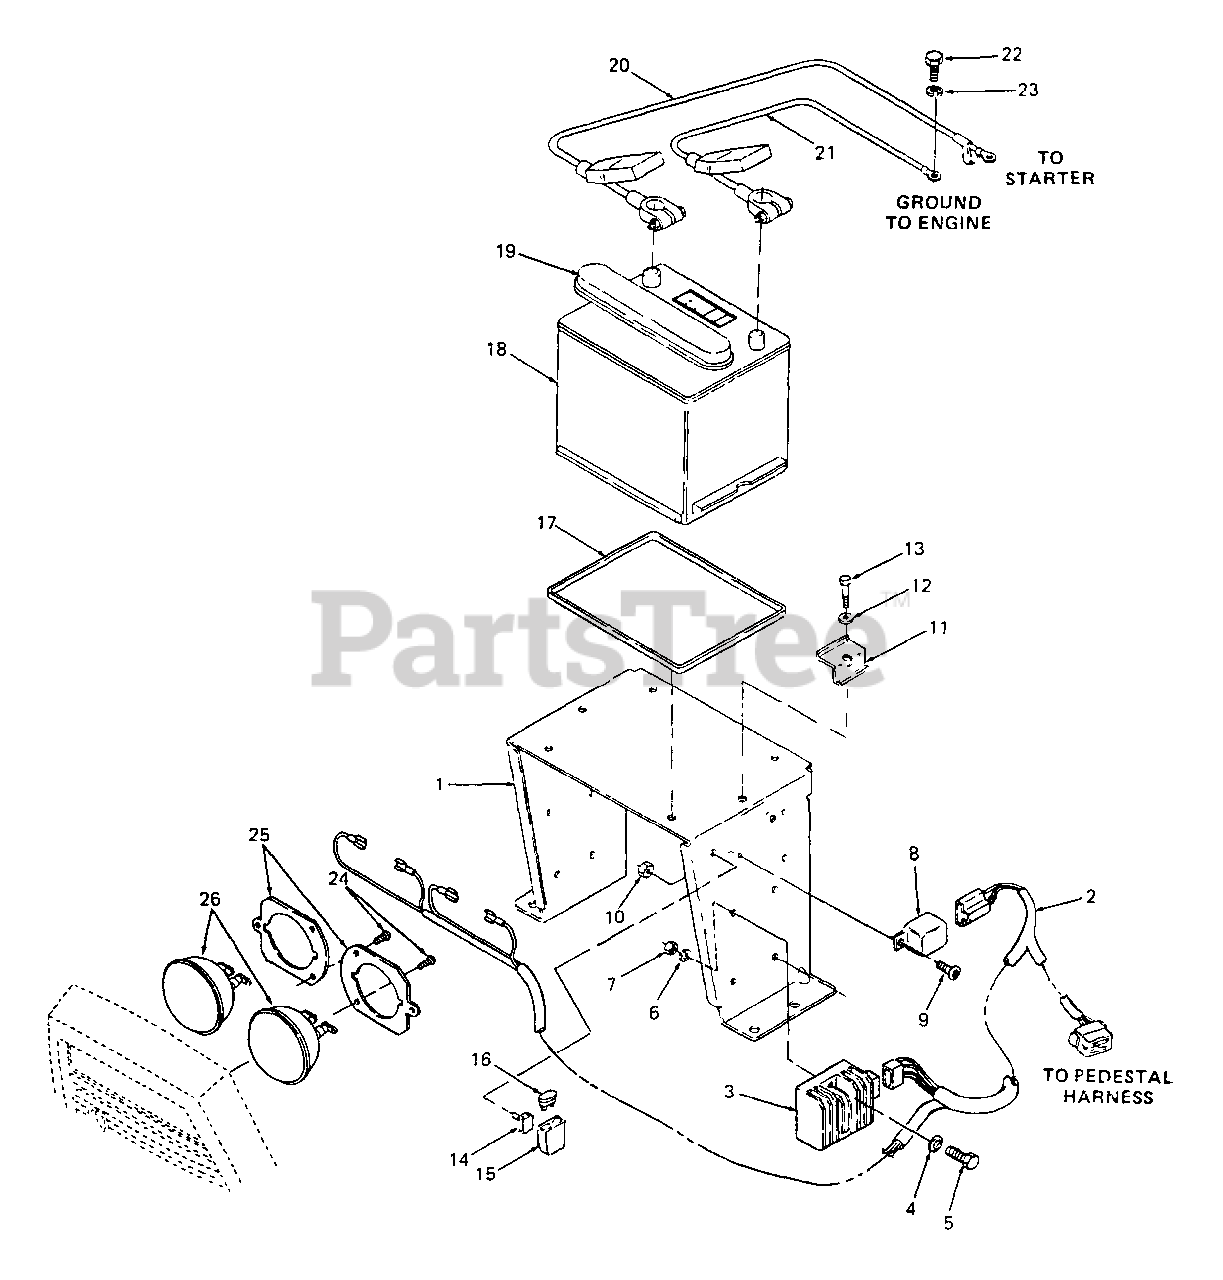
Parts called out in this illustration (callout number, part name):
1	Tray Assy, Battery
2	Harness, Main Wire
3	Regulator, Voltage
4	Washer, Bell, .265 x .75 x .062 Thk
5	Screw, Hex Cap, 1/4-20 x 1.25 Lg
6	Washer, Lock, 1/4
7	Nut, Hex, 1/4-20 GR5
8	Relay
9	Screw, Truss Mach, #10-24 x .50 Lg
10	Nut, Hex, Center Lock, #10-24
13	Screw, Hex Cap, 5/16-18 x 2.0 Lg
14	Clip, Fuse Holder Mtg
15	Holder, Fuse
16	Fuse, 20 Amp
17	Tray, Battery
18	Battery
19	Cap, Battery Vent
20	Cable, Positive Battery
21	Cable, Negative Battery
22	Screw, Hex Cap, M8 x 1.25 x 20 MM GR5
23	Washer, Lock, 3/8
24	Screw, Pan Hd Tapp, #12 x .50 Lg
26	Headlamp, Sealed Beam
